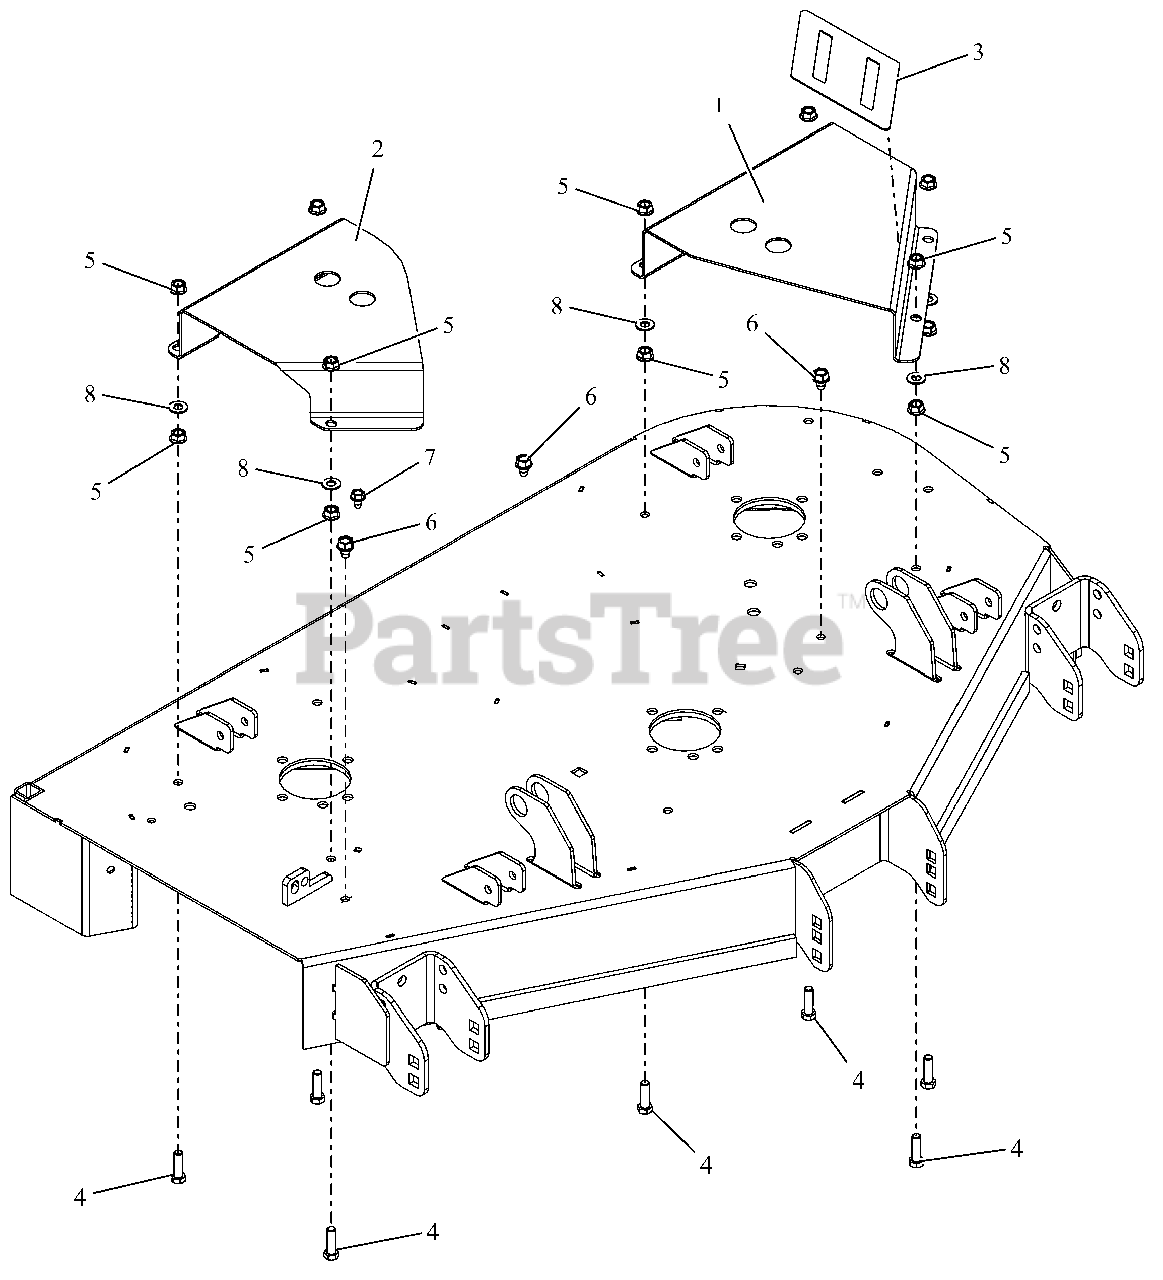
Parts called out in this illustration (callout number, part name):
1	COVER, BELT 44" LH
2	COVER, BELT 44" RH
3	GRIP, TAPE 44 BELT COVER
4	@BLT-HEX .38-16X1.25 GR5 YWZC
5	@NUT-SPNLK-FLG .375-16 YWZC
6	@SCR-TAP .38-16X.50 HWH TR YWZ
7	@SCR-TAP .31-18X.50 HWH TR YWZ
8	@WSHR-FL-STL.406X.812X.065 YWZ
